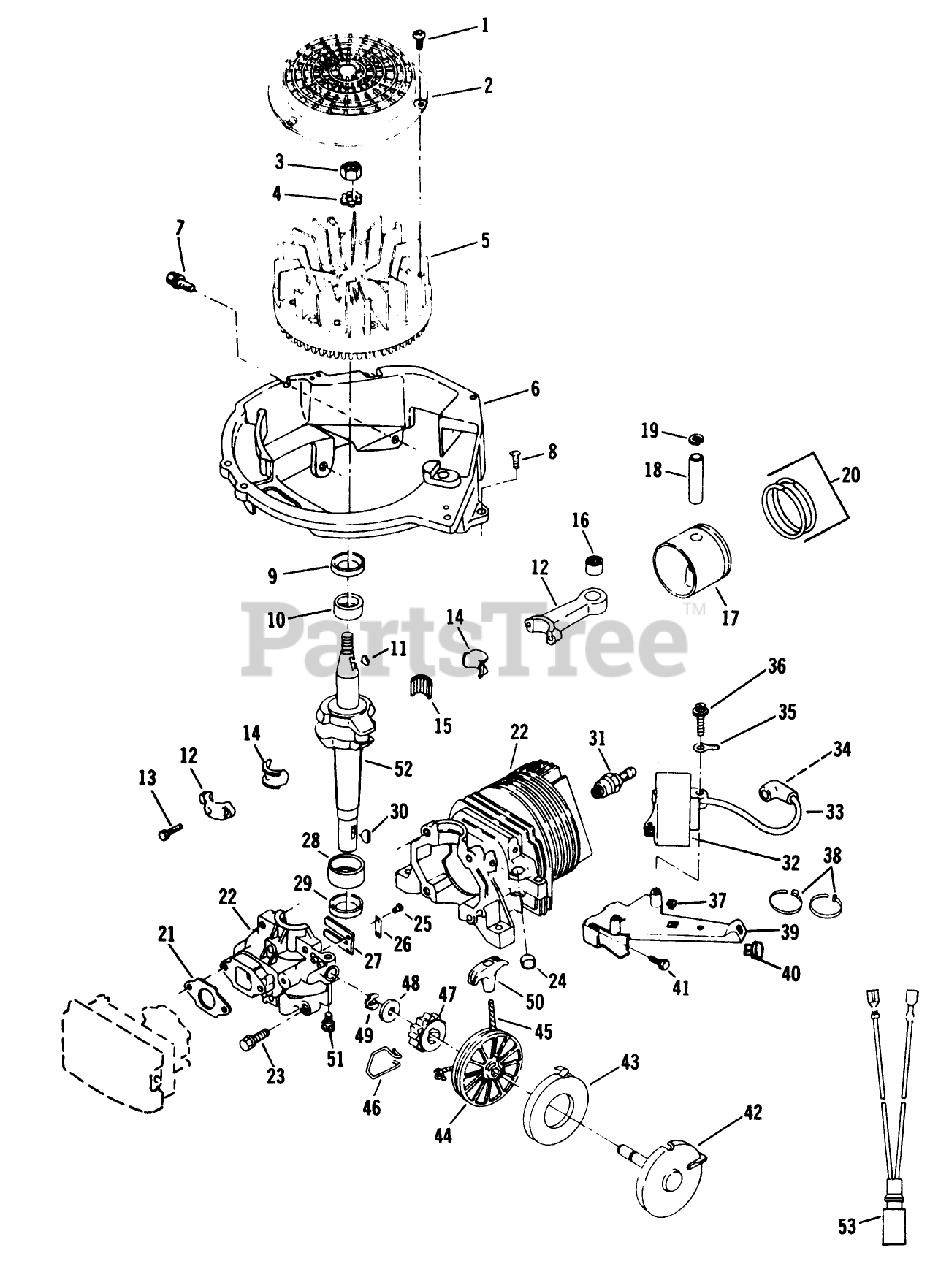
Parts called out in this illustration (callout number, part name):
1	SCREW F
2	SCREEN F'WHEEL S
7	SCREW-SEMS
8	SCREW F
10	BEARING V
13	SCREW-HSH
14	LINER ASM
16	BEARING AY F
19	RING-RETAINING
21	GASKET CARB S
23	SCREW S
24	PLUG-CORE VF
26	PLATE-BACKUP, REED
28	BEARING V
29	SEAL-OIL
33	HT LEAD&COVER XEV
35	TERMINAL S
37	NUT-CLIP
40	NUT-CLIP
44	PULLEY STARTER S
46	SPRING F
48	WASHER S
50	HANDLE STARTER S
53	WIRE HARNESS
